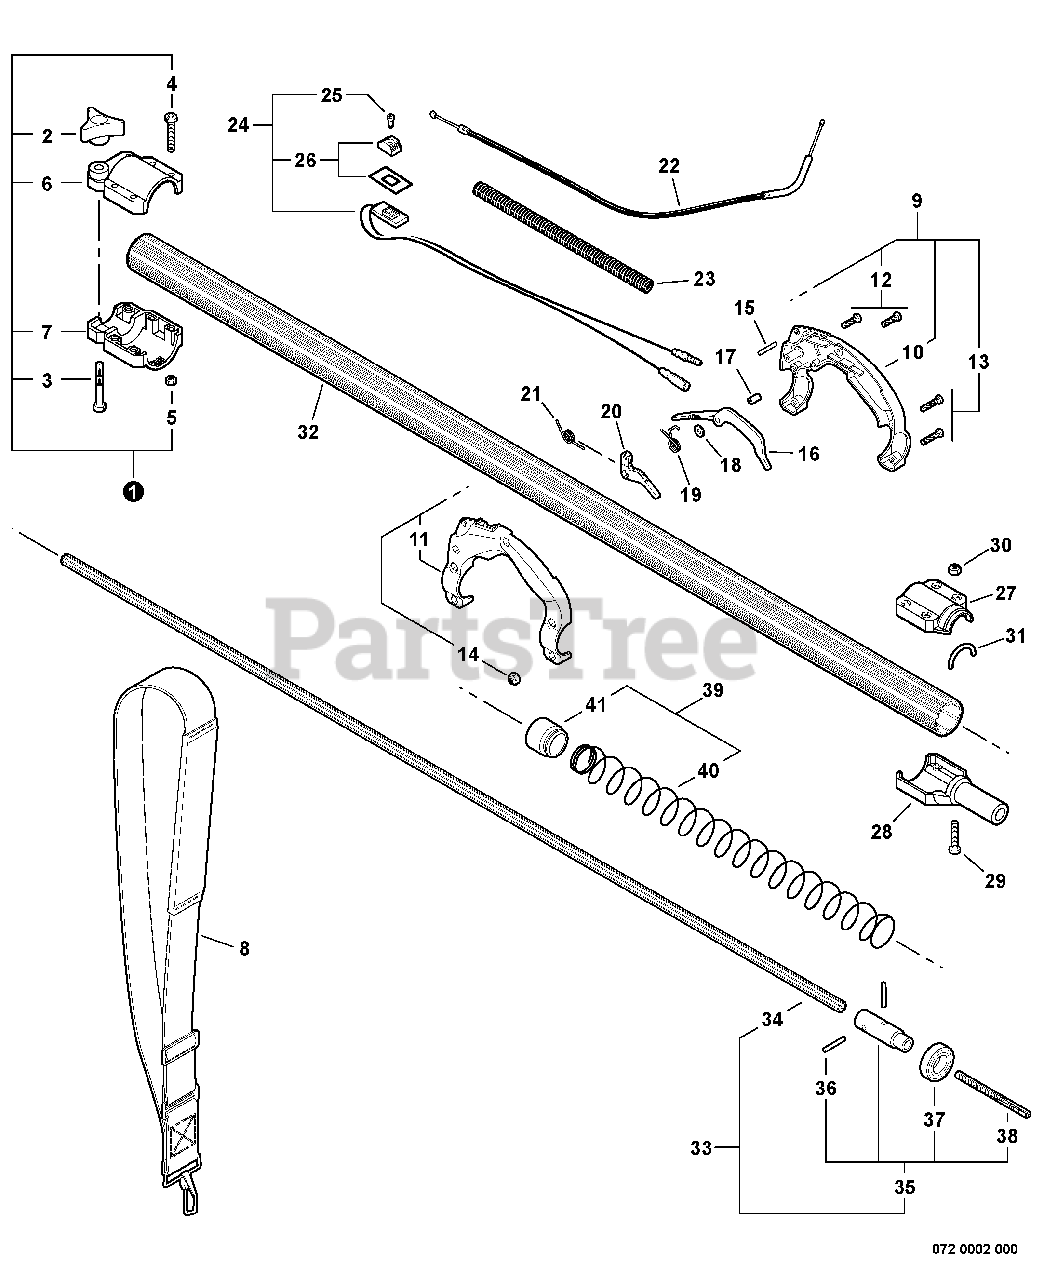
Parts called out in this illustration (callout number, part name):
1	COLLAR ASSY
2	THUMBSCREW
4	SCREW - 10-24 X 1-1/4"
5	LOCKNUT - 10-24
6	COLLAR, MAIN PIPE - UPPER
7	COLLAR, MAIN PIPE - LOWER
8	SHOULDER STRAP ASSY
9	HANDLE ASSY - REAR
10	HANDLE, REAR - LEFT
11	HANDLE, REAR - RIGHT
12	SCREW - 10-24 X 1-1/4"
14	LOCKNUT - 10-24
15	PIN - LOCATING
16	LOCKOUT, THROTTLE
17	COLLAR - 5
18	WASHER - 5
19	SPRING, LOCKOUT LEVER
20	TRIGGER, THROTTLE
21	SPRING, TRIGGER
22	CABLE, THROTTLE
23	TUBE, PROTECTIVE - CORRUGATED
24	IGNITION SWITCH ASSY
25	SCREW - 3X10
26	KNOB, SWITCH - ORANGE
27	CAP, LOWER SHAFT TUBE ADAPTER
28	ADAPTER, LOWER SHAFT TUBE
30	LOCKNUT - 10-24
32	PIPE, MAIN - ORANGE
33	DRIVESHAFT ASSY
34	DRIVESHAFT
35	SHAFT CONNECTOR KIT
37	BEARING, BALL - 6002
39	FLOATING BUSHING ASSY
41	BUSHING, FLOATING
